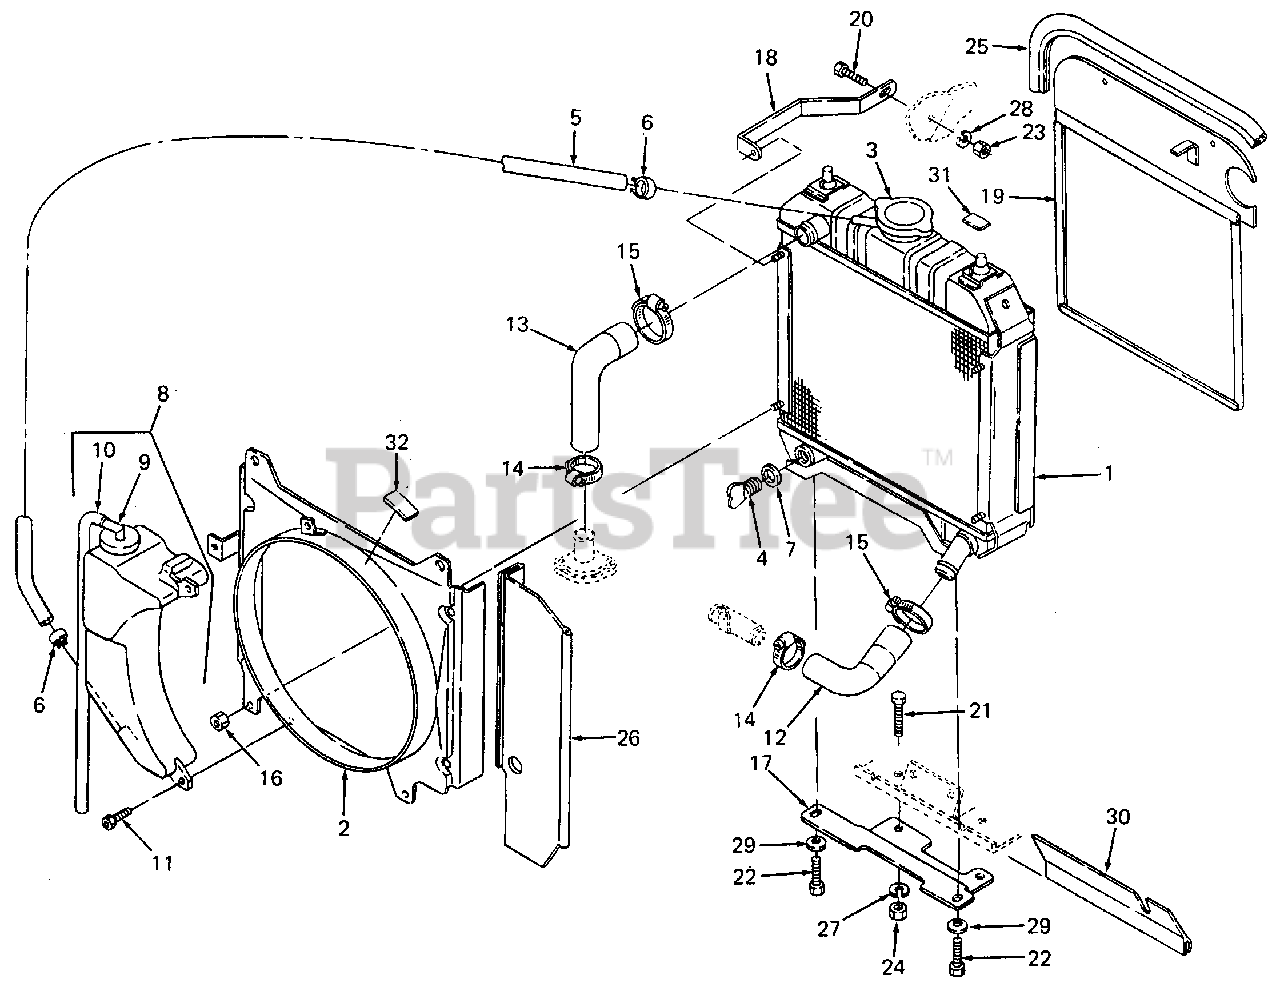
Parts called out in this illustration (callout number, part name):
1	Radiator Assy
5	Pipe, Water Overflow
8	Tank Assy, Reserve
10	Pipe, Overflow
17	Mount, Radiator
18	Brace, Radiator
19	Heat Baffle Assy
20	Screw, Hex Cap, 1/4-20 X .62 Lg GR5
21	Screw, Hex Cap, 5/16-18 X .75 Lg GR5
22	Screw, Hex Cap, M10 X 1.25 X 25 mm Lg GR8
23	Nut, Hex, 1/4-20 GR5
24	Nut, Hex, 5/16-18 GR5
25	Strip, Trim
26	Flap, Radiator Air RH
27	Washer, Lock, 5/16 Dia
28	Washer, Lock, 1/4 Dia
29	Washer, Bell, .45 X 1.0 X .062
30	Flap, Radiator Bottom
31	Label, Radiator
32	Label, Radiator
